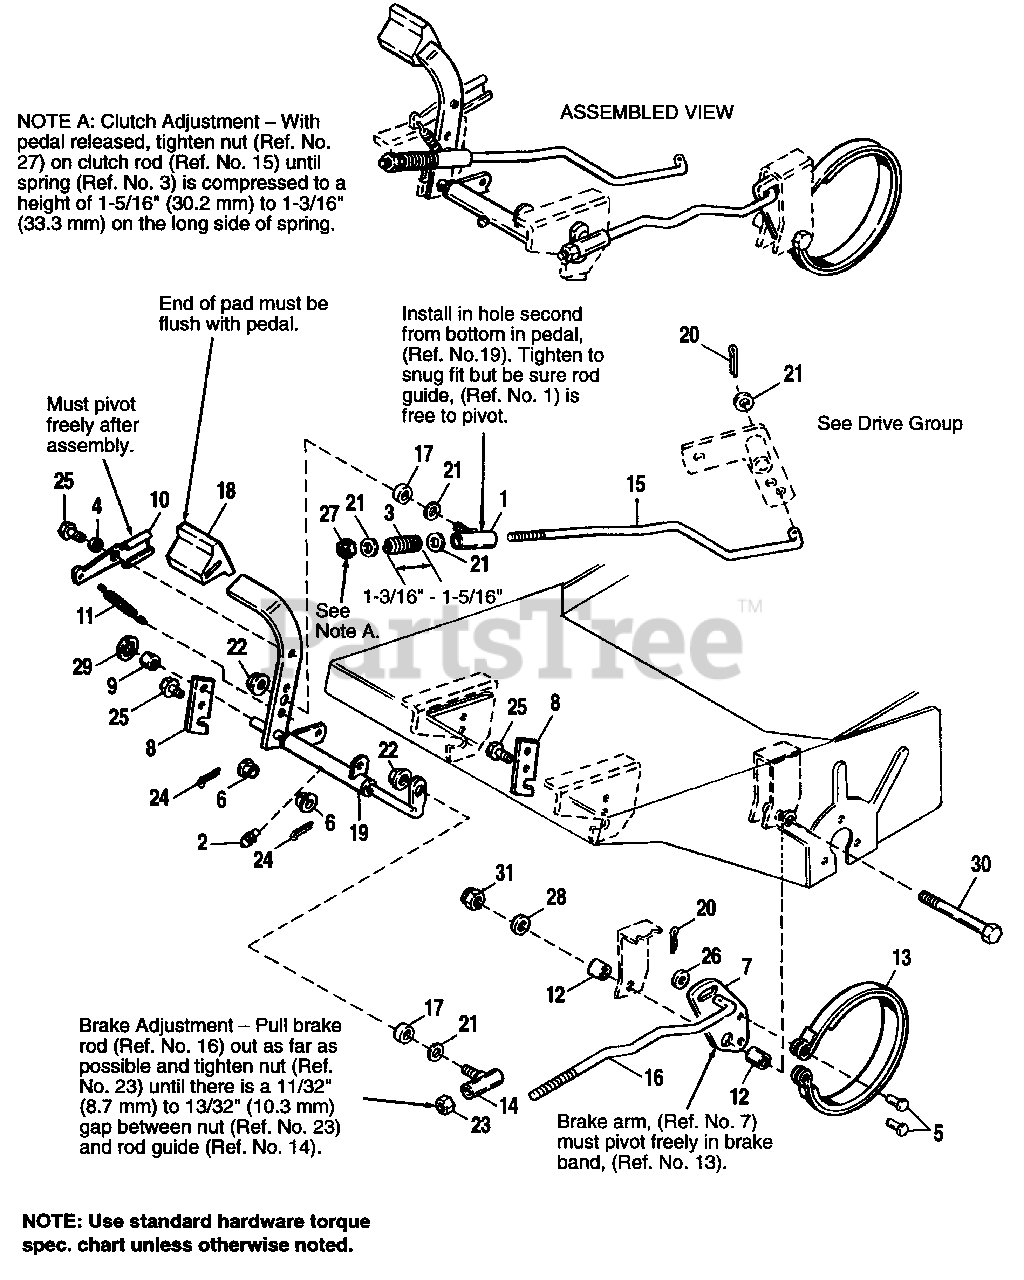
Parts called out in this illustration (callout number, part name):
1	GUIDE ASSY., Rod
2	FITTING, Grease
6	BUSHING, Nylon, Split
7	LINK, Brake Arm
8	BRACKET, Brake
10	LATCH, Brake
13	BAND ASSY., Brake
14	GUIDE ASSY., Rod
15	ROD, Clutch
18	PAD, Pedal
19	SHAFT ASSY., Brake
20	PIN, Cotter, 3/4
21	WASHER, 5/16
22	NUT, Hex, ESNA, Lock, 5/16-18
23	NUT, Hex, Lock, 3/8-16
24	PIN, Cotter
25	SCREW, Taptite, 5/16-18 x 1/2
26	WASHER, 3/8
27	NUT, Hex, Centerlock, 5/16-18
28	WASHER, 1/2
30	CAPSCREW, 1/2-13 x 3-1/2, Gr. 5
31	NUT, Hex, ESNA, Lock, 1/2-13
